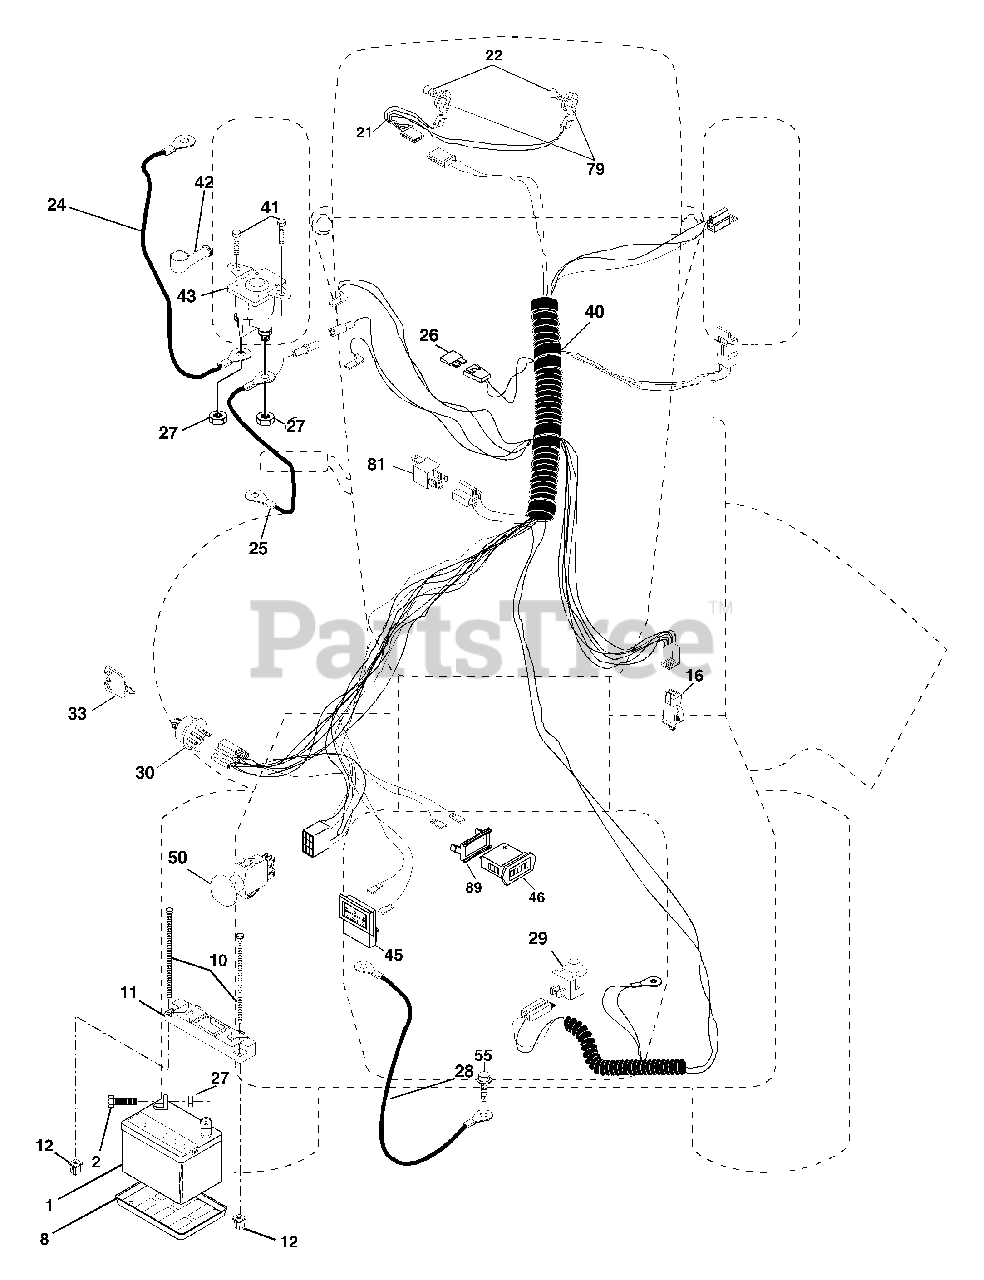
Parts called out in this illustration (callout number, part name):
1	Battery
2	Bolt Hex Hd 1/4-20 UNC X 3/4
8	Tray, Battery
10	Bolt, BTR FRT 1/4-20 x 7.5
11	Hold Down Battery, Front
12	Nut, Push, Nylon
16	Switch Interlock Push-In
21	Harness Asm Light W/4152j
22	Bulb Light #1156
24	Cable Battery
25	Cable Batterywire
26	Fuse
27	Nut Keps Hex 1/4-20 Unc
28	Cable Ground
29	Switch Plunger Normal OP Olive
30	Switch Ign 4 pos w/lights
33	Key Ign
40	Harness Ign.
41	Bolt Blk Fin Hex 1/4-20 x 1/2
42	Cover Terminal Red
43	Solenoid
45	Ammeter Rectangular
46	Hourmeter Snap-In
50	Switch, PTO
55	Screw Thdrol 5/16-18 x 1/2
79	Bulbholder
81	Relay Asm
89	Bracket Snap-In Hourmeter
